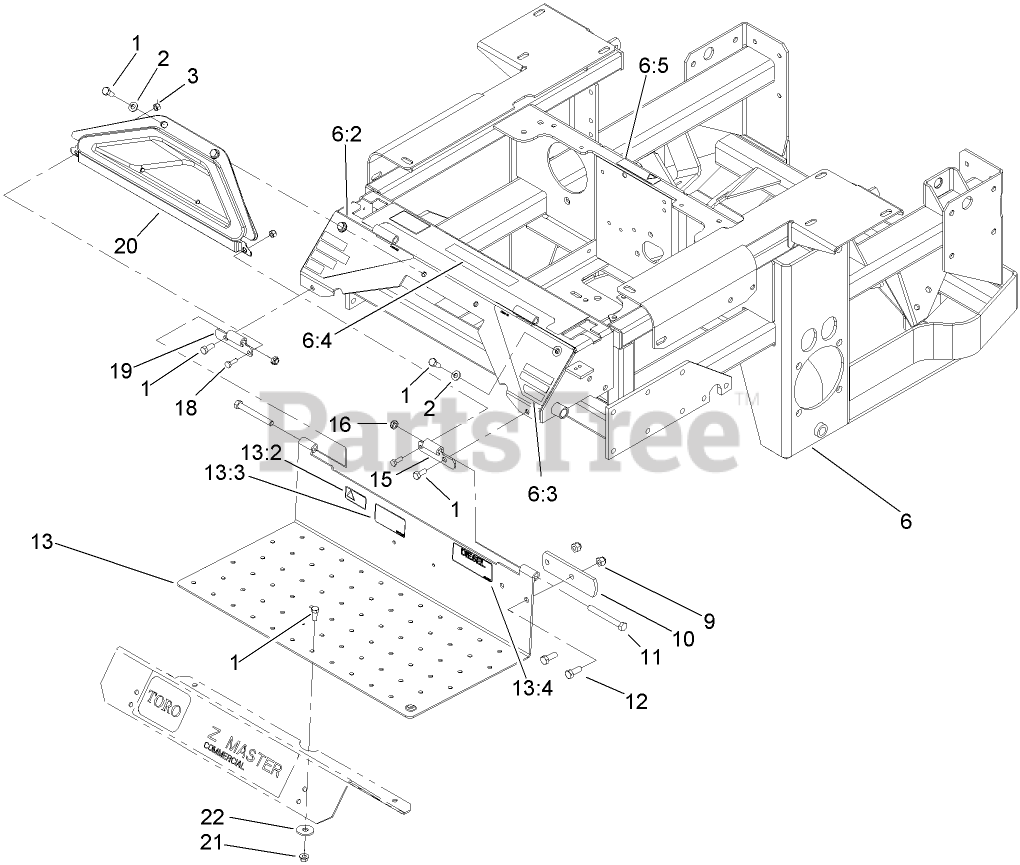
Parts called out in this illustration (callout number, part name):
1	SCREW-HH
2	WASHER-FLAT
3	NUT-LOCK, NI
6	MAIN FRAME ASM
6:2	DECAL-DANGER, LEFT
6:3	DECAL-WARNING, RIGHT
6:4	DECAL-CONSOLE, TOP
6:5	DECAL-WARNING
9	NUT-LOCK, NI
10	STOP-BRAKE, PARK
11	SCREW-HH
12	SCREW-HH
13	FLOORPAN ASM
13:2	DECAL-PROTECTION, EAR
13:3	DECAL-LOCATION, MANUAL
13:4	DECAL-DIESEL
15	Hinge-Floorpan, LH
16	NUT-LOCK, NI
18	SCREW-HH
19	Hinge-Floorpan, RH
20	Pocket
21	NUT-HF
22	WASHER
